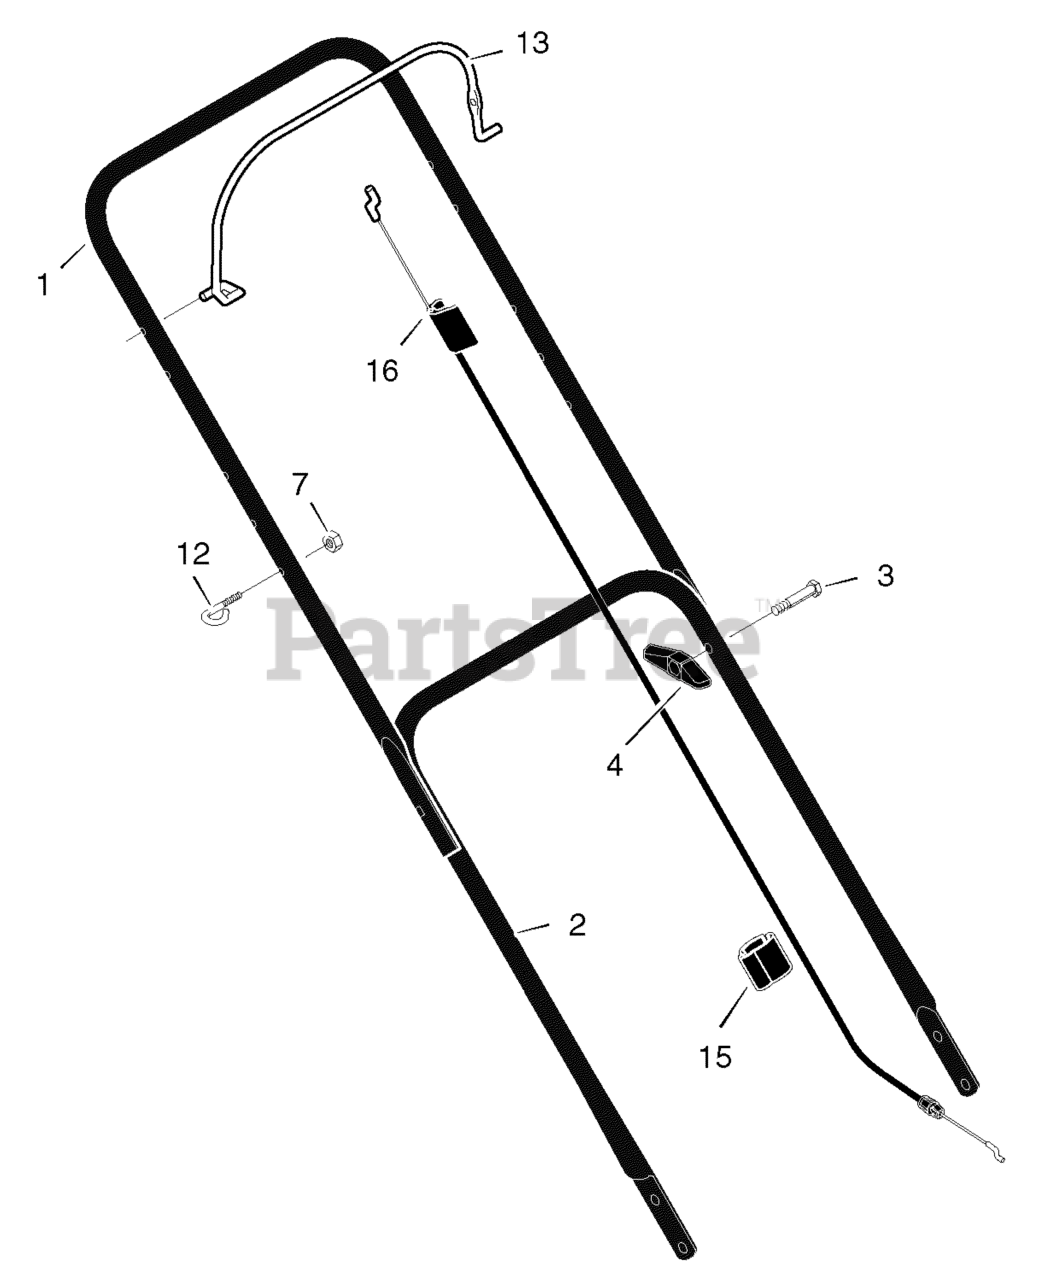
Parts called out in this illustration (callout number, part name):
1	Handle, Upper (Black)
1	Handle, Upper (Gray)
2	Handle, Lower (Black)
2	Handle, Lower (Gray)
4	Knob, Plastic
7	Locknut
12	Guide, Rope
13	Lever, Engine Stop
15	Clip, Cable
16	Engine Stop Cable
